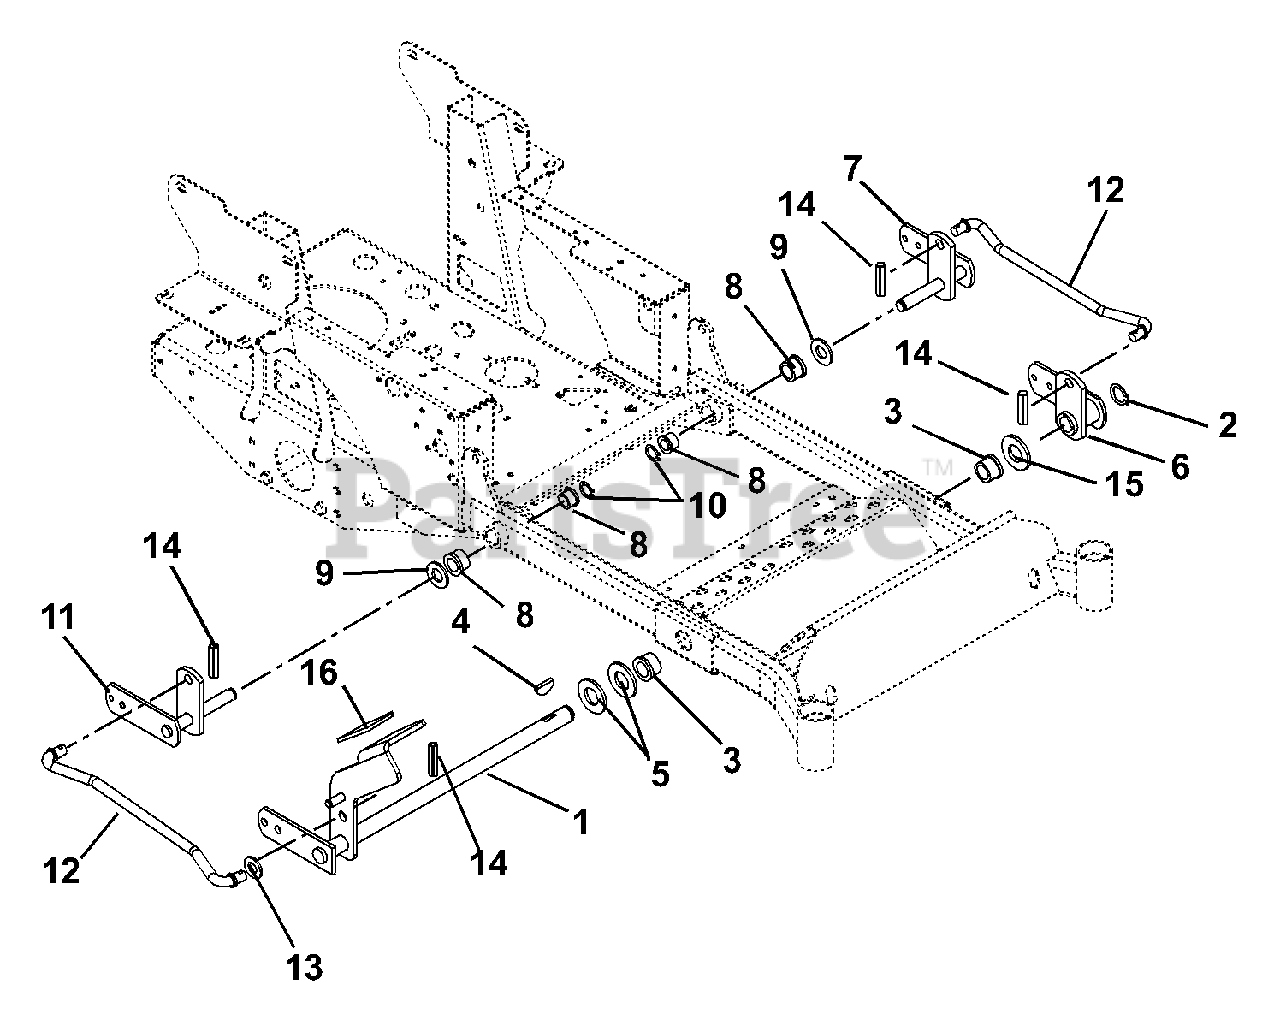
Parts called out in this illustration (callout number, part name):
1	WMT, FRONT MOWER LIFT
2	RG-RTNG-EXT 1.00X.078
3	BSHG-FLG1.020X1.385X.75X1.75NY
4	KEY-WDRF .25X1.00 HRD #15
5	WSHR-FL-STL- 1.062X2.0X.134 YZ
6	WMT, FRONT MOWER LIFT-LH
7	WMT, REAR LIFT ARM -LH
8	BSHG-FLG .762X1.0X.580X1.48 NY
9	WSHR-HDND-THRST .758X1.23X.031
10	RG-RTNG-EXT .689X.078
11	WMT, REAR LIFT ARM - RH
12	ROD, LIFT ASSIST 16.35"
13	@WSHR-FL-STL.656X1.31X.095 YWZ
14	PIN-ROLL .250X1.25 STNLESS STL
15	WSHR-HDND-THRUST 1.00X1.55X.03
16	GRIP, PEDAL 1.50 X 3.00
